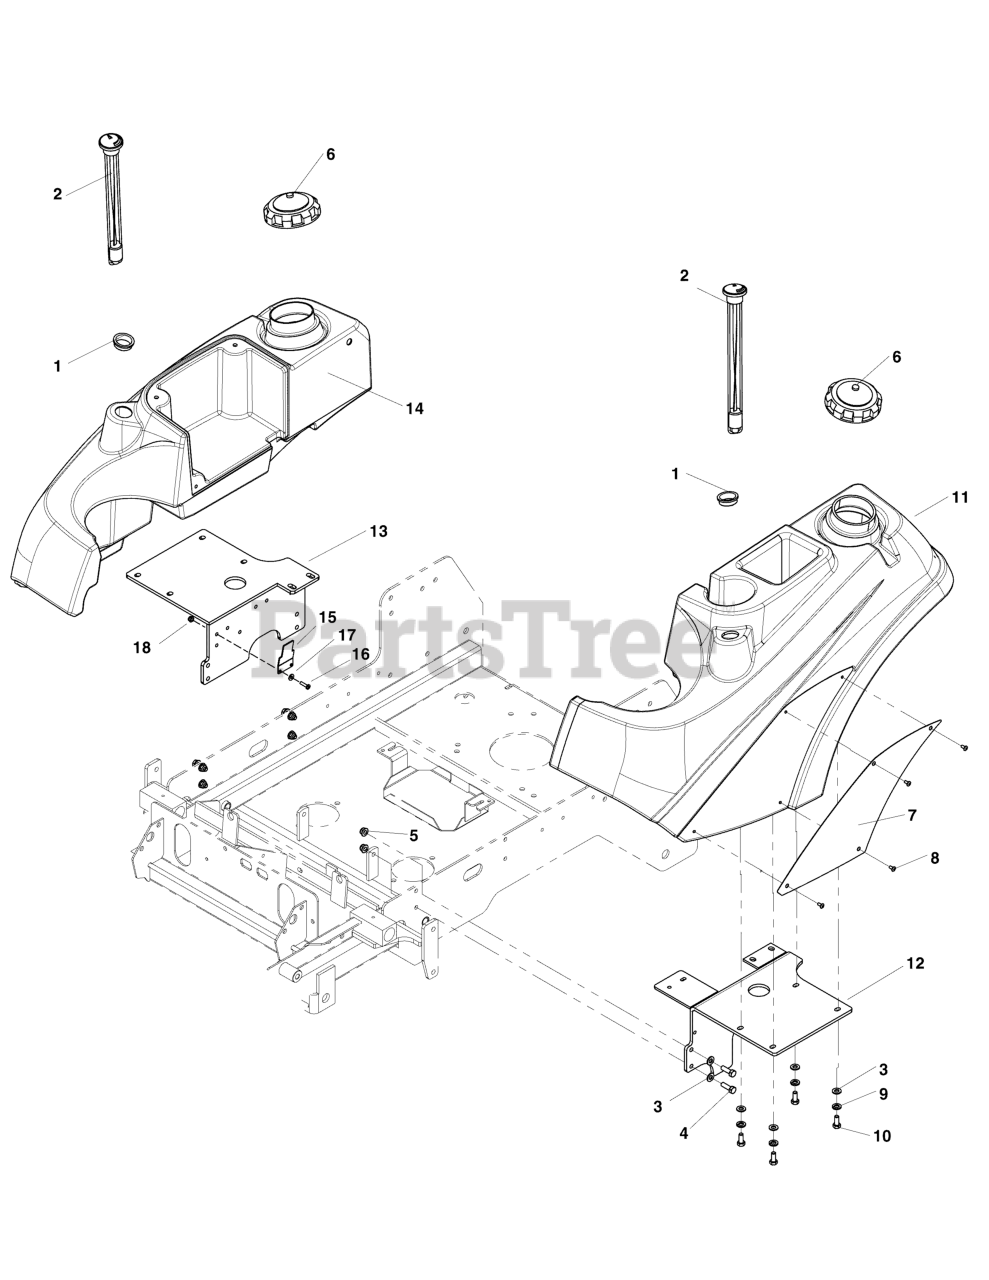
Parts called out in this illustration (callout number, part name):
1	GROMMET, FUEL GUAGE
2	GAUGE, FUEL, 12
3	WASHER, 5/16" SAE
4	BOLT, 5/16-18 X 1" GD5 YZ
5	NUT, 5/16-18 X 1" GD5 YZ
6	FUEL CAP, 3-1/2", MANAGED VENT OUT, 12"
6	CAP, GASOLINE, VENTED
7	BADGE, IS2000 - IS3000 - RED
8	SCREW, #10-24 X 3/8" ALLEN BHBZ
9	WASHER, 5/16 LOCK CZ
10	BOLT, 5/16-18 X 3/4 GD5
11	TANK, FUEL, LH
12	WELD, TANK MOUNT - LH - BLK
13	WELD, TANK MOUNT - RH - BLK
14	TANK, FUEL, RH
15	PLATE, FUSE BLOCK TAB
16	SCREW, #10-24 X 3/4 ROUND
17	WASHER, #10 SAE
